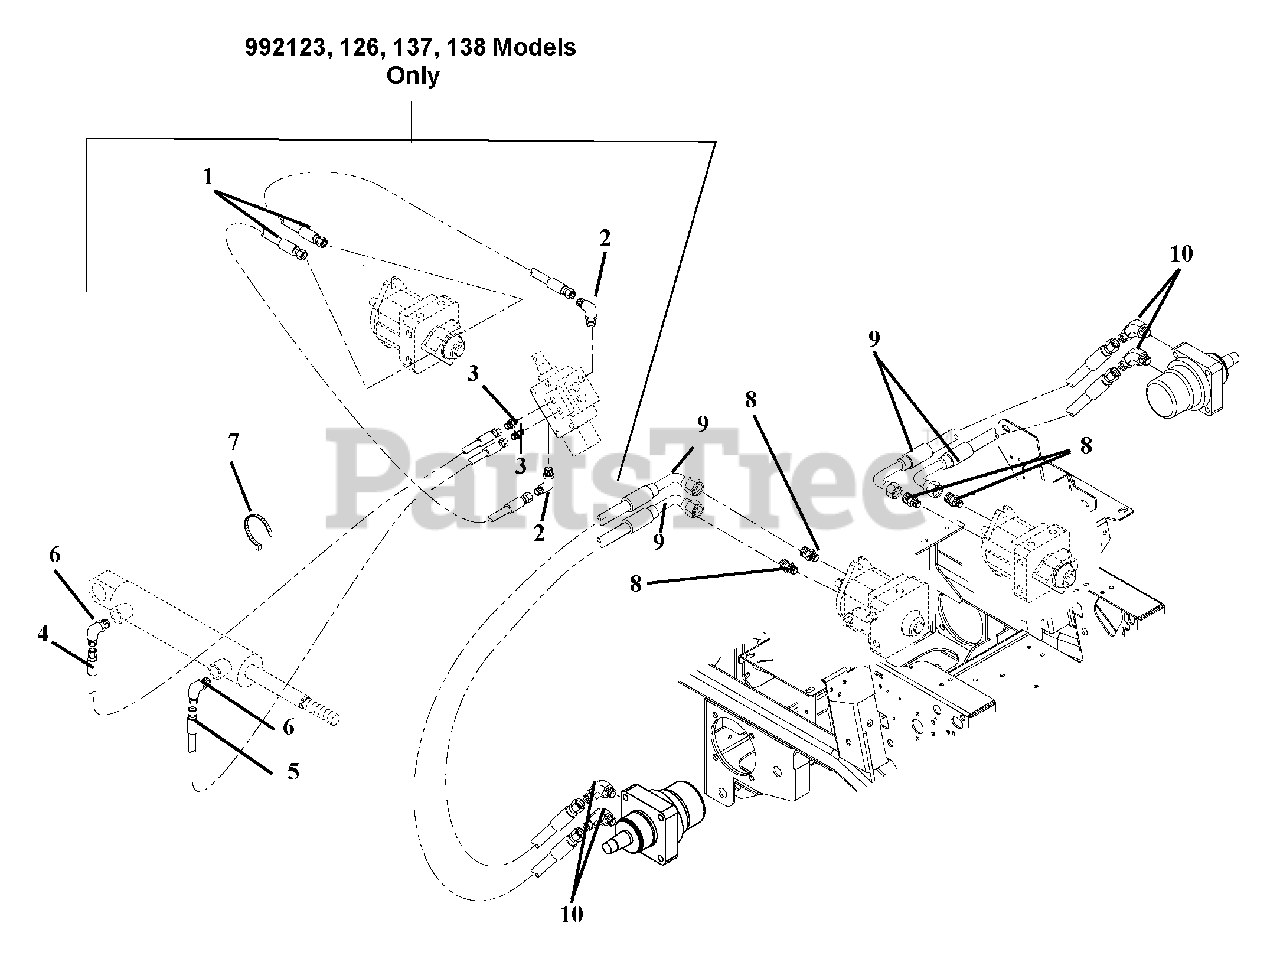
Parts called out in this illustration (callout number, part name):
1	Hose, Hydraulic
2	Hydraulic, Fitting Elbow
4	Hose, Hydraulic
5	Hose, Hydraulic
6	Fitting, Hydraulic
7	Cable Tie
8	Adapter, Face Seal 8 x 8 .50 O-Ring
9	Hose, Hydraulic .50
10	Adapter-Hydraulic Steel .875 to .75
